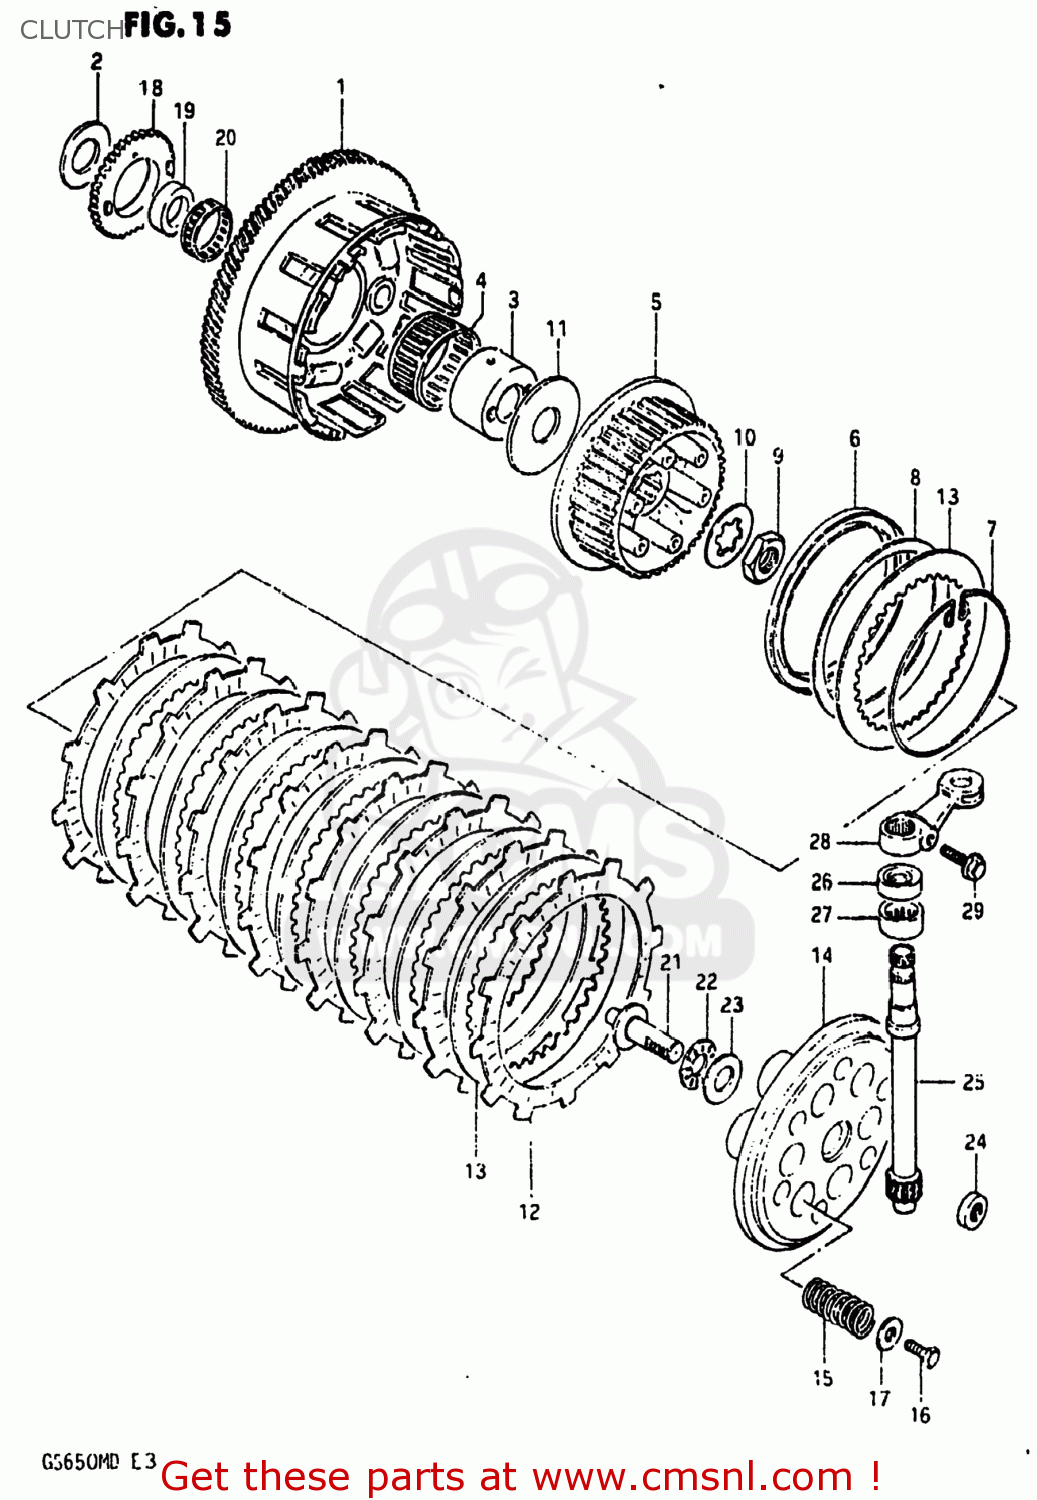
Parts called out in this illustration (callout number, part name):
1	GEAR ASSEMBLY,PRIMARY DRIVE
2	WASHER
3	SPACER
4	BEARING
5	HUB,CLUTCH SLEEVE
6	SEAT,WAVE WASHER
7	RING,STOPPER
8	WASHER
9	NUT
10	WASHER,LOCK
11	WASHER(25X66X3.5)
12	PLATE,CLUTCH DRIVE (MCA)
13	PLATE,CLUTCH DRIVEN(T:2.0) (NAS)
14	DISC,CLUTCH PRESSURE
15	SPRING
16	BOLT, UPPER
17	WASHER
18	GEAR,ENG OIL PUMP DRIVE(NT:34)
19	SPACER,OIL PUMP DRIVE GEAR
20	BEARING(36X40X10)
21	RACK,CLUTCH RELEASE
22	BEARING(15X28X2)
23	WASHER
24	SEAL,OIL(10X16X5)
25	PINION,CLUTCH RELEASE
26	OIL SEAL
27	BEARING(15X22X12)
28	ARM,CLUTCH RELEASE
29	BOLT,REAR
